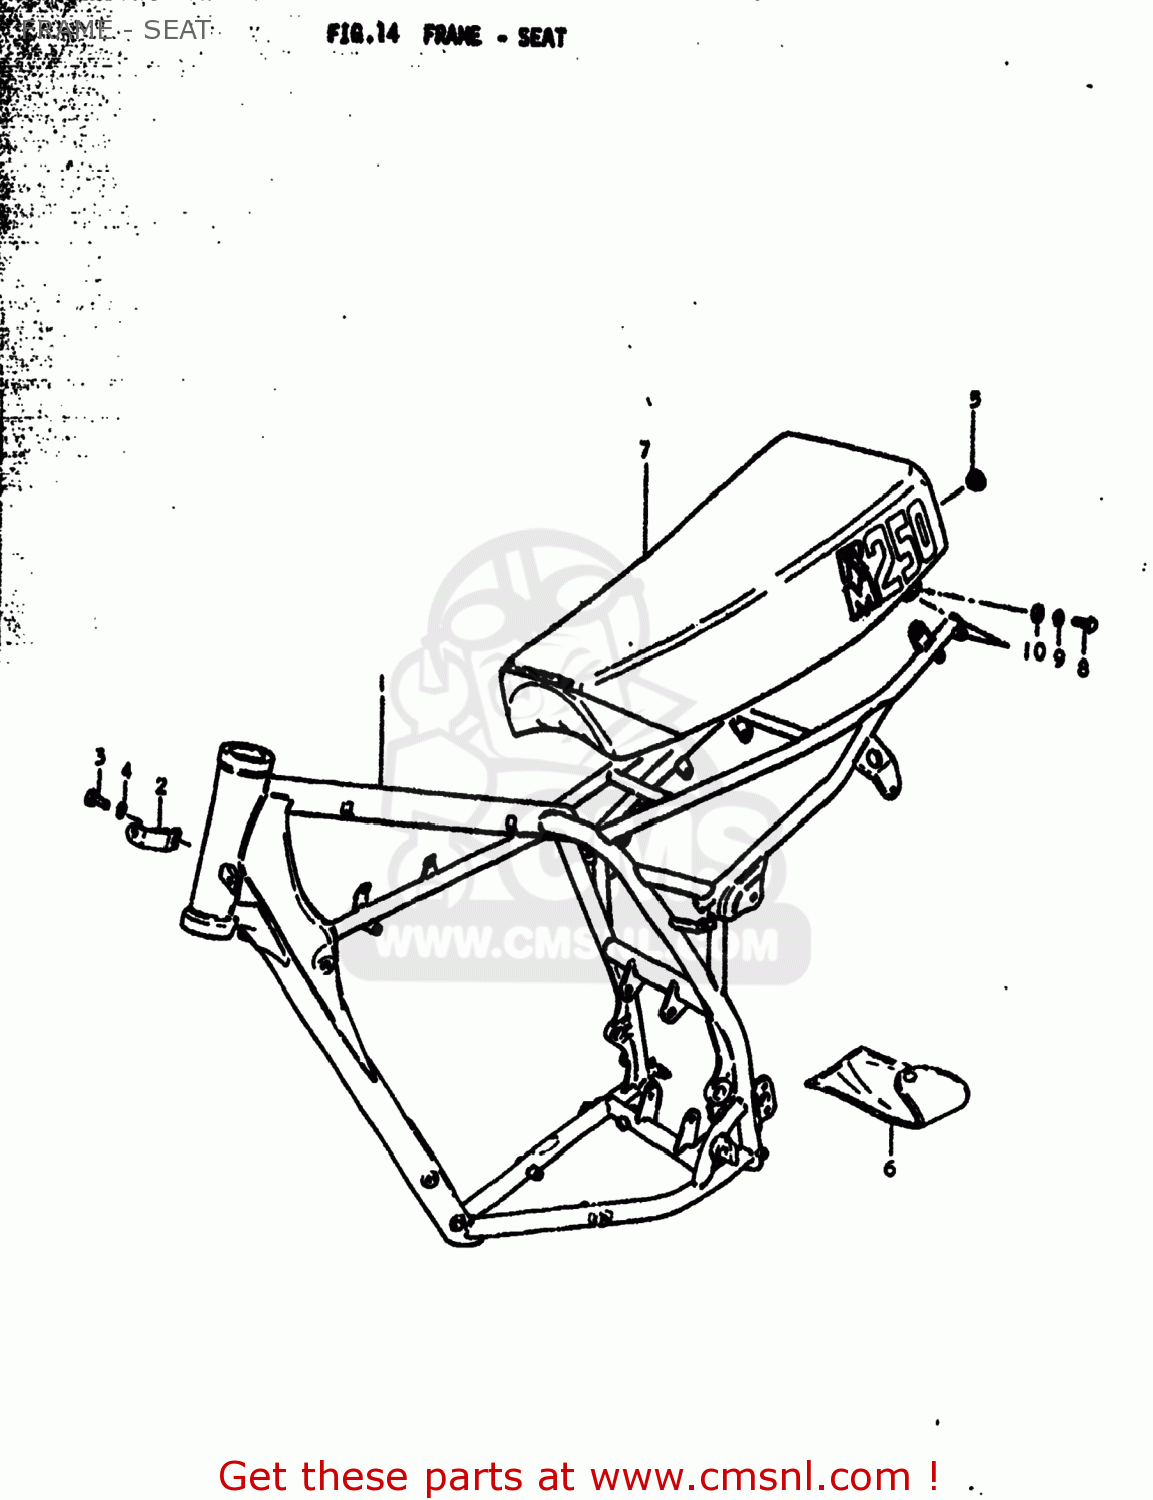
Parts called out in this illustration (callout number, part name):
1	FRAME
2	PLATE,ENGINE MOUNTING
3	BOLT
4	LOCK WASHER
5	PLUG(OD:19)
6	TOOL SET
7	SEAT ASSEMBLY
8	BOLT, UPPER
9	LOCK WASHER
10	WASHER(6.5X18X1)
